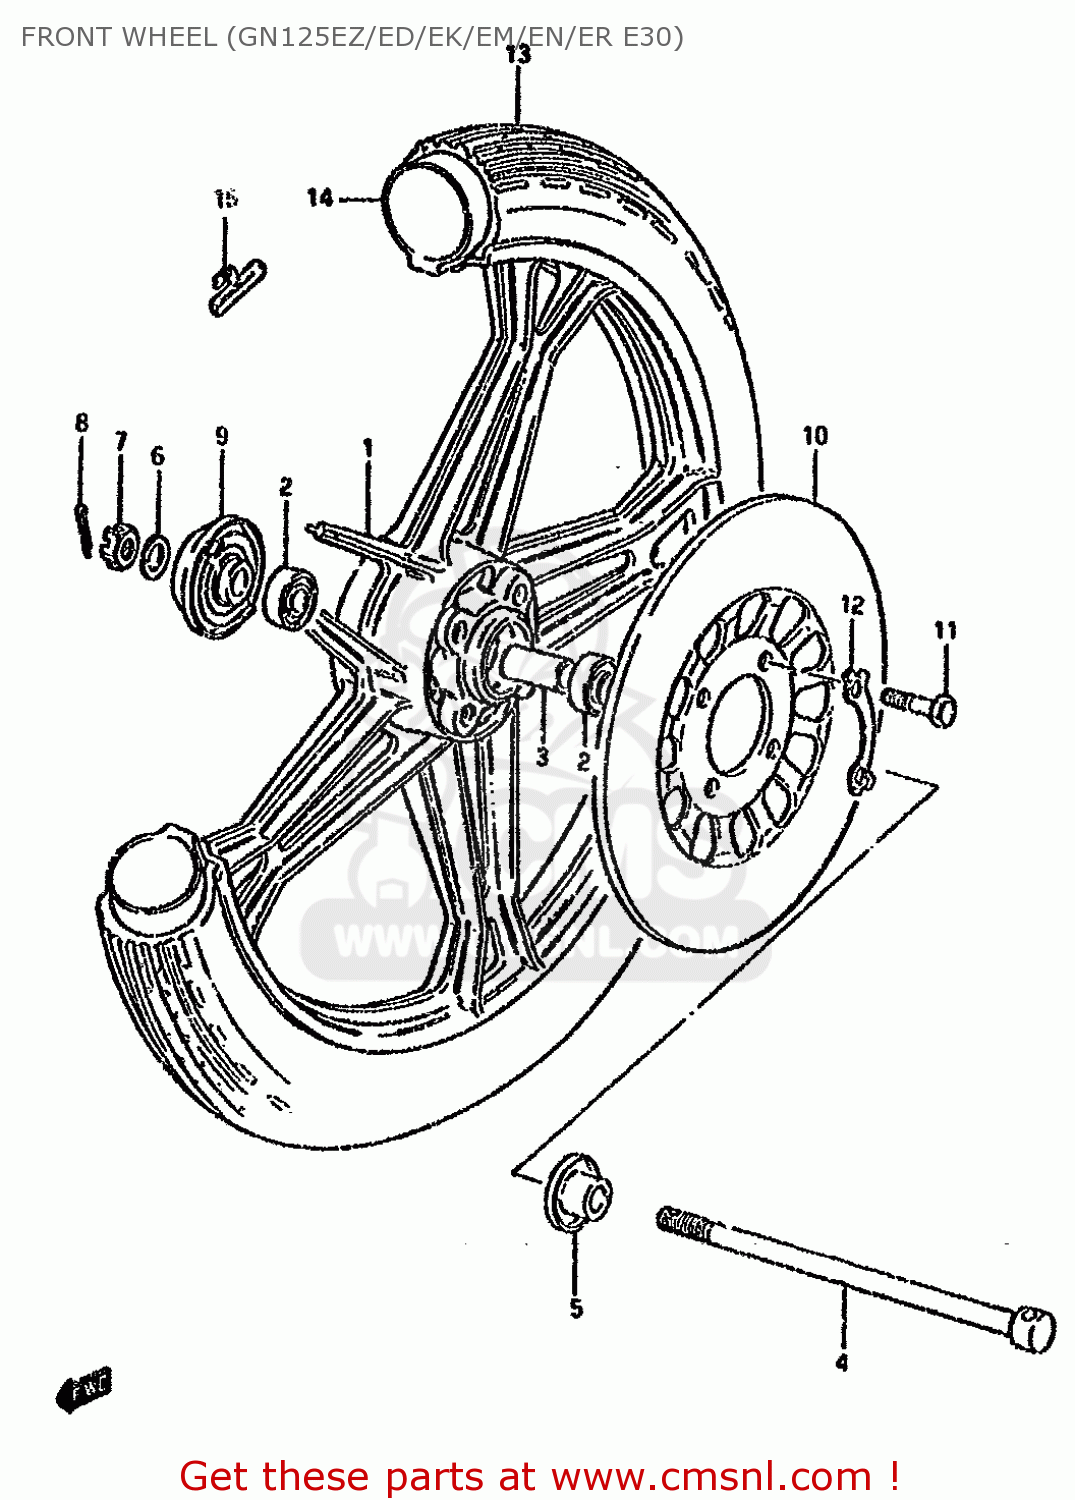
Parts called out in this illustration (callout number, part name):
1	WHEEL,FR(1.60X18)
2	BEARING
3	SPACER (12.6X19X52)
4	AXLE,FR
5	SPACER,FR AXLE,L
6	WASHER
7	NUT
8	COTTER PIN
9	BOX ASSY,SPEEDOMETER GEAR
10	DISC,FR BRAKE
11	BOLT(8X30)
12	WASHER
13	TIRE,FRONT
14	TUBE,INNER
15	BALANCER,WHEEL
